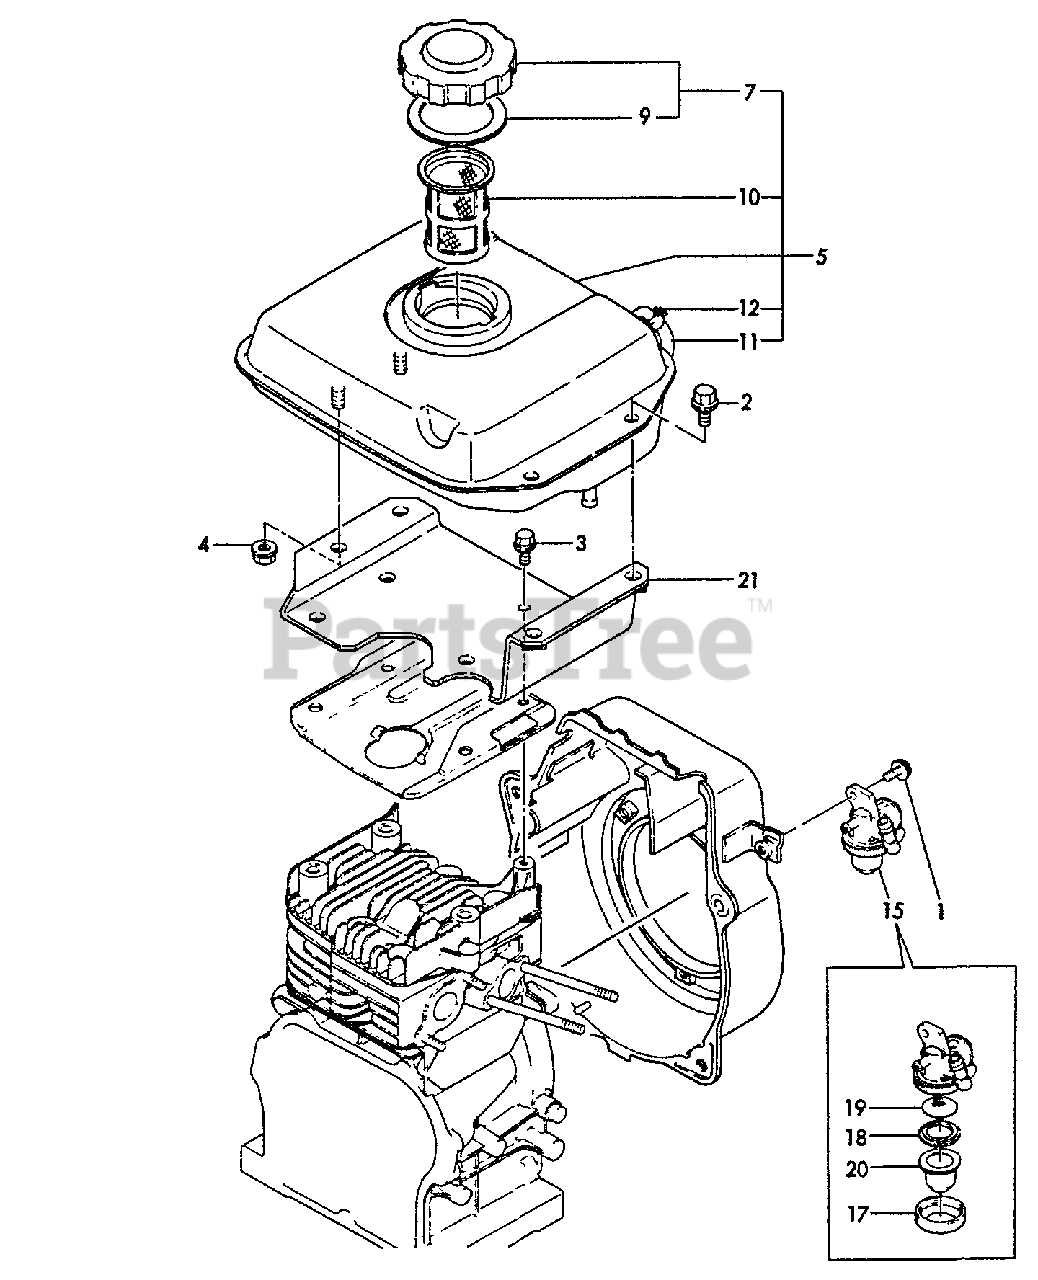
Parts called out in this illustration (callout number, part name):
1	BOLT - 6X12 -- PLATED
2	BOLT - 8X14 -- PLATED
3	BOLT - 6X8 -- PLATED
4	NUT - 8
5	FUEL TANK ASSY
7	CAP ASSY
9	GASKET
10	STRAINER, FUEL
11	GAUGE, LEVEL
12	CLAMP, HOSE - 9
15	FUEL COCK ASSY
17	RETAINER
18	GASKET
19	STRAINER, FUEL
20	BOWL, STRAINER
21	BRACKET, FUEL TANK
